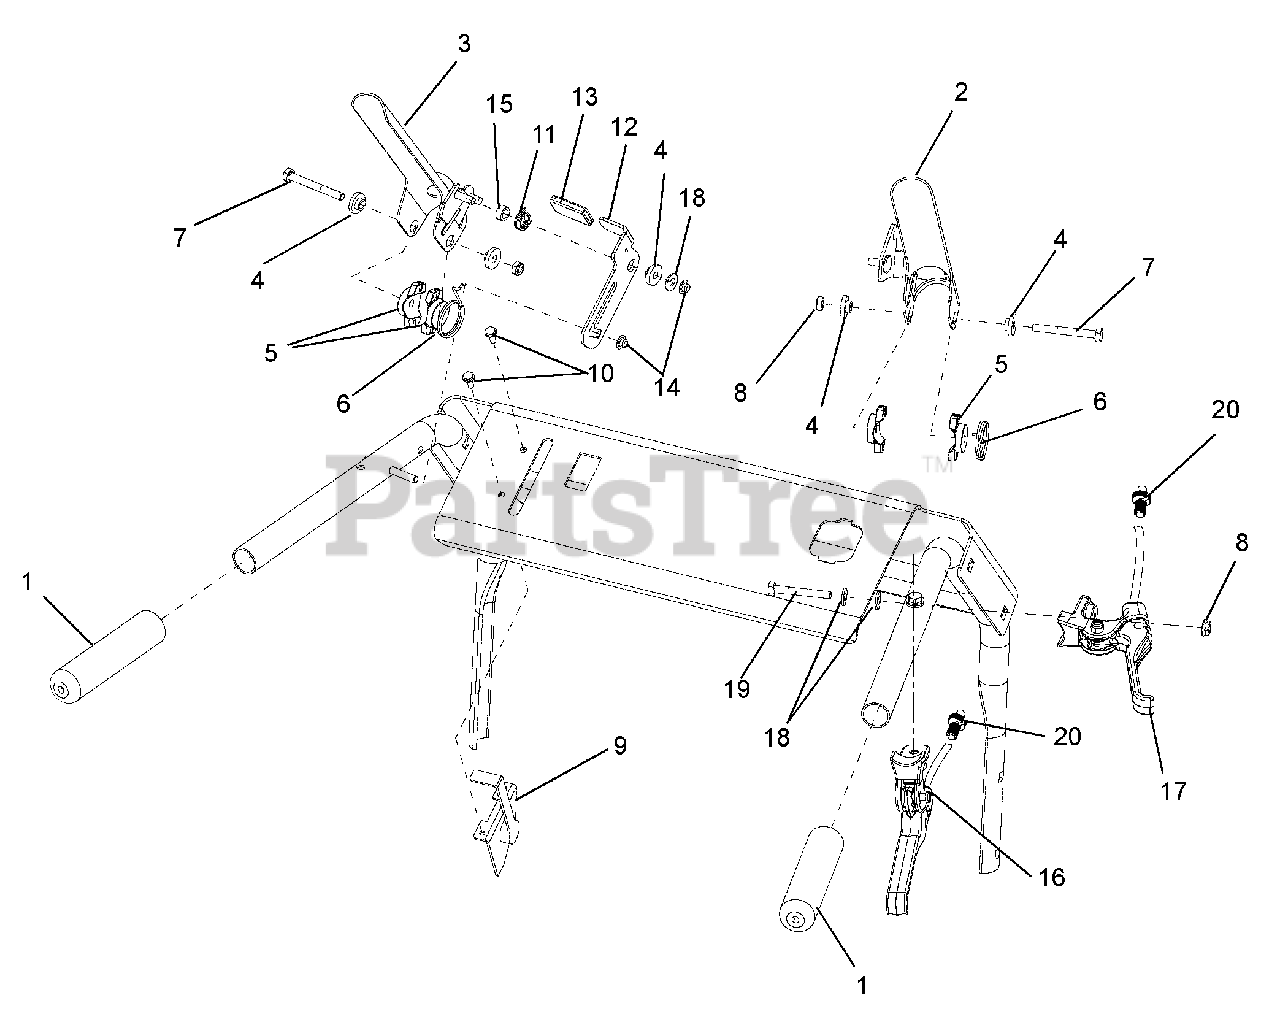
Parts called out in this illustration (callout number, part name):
1	Grip, Handle
2	Paddle, Pillow Brake
3	Weldment, Paddle Left Hand
4	Bushing, Flange .266 x .42 x .150 x .750
5	Spacer, Handlebar
6	Spring, Torsion
7	Bolt, Hex .25-20 x 2.25
8	Nut, Nylon Jam .250-20
9	Cable, Throttle/Choke
10	Screw Tapping 10-24 x .38
11	Spring, Torsion
12	Bracket - Lever, Interlock
13	Grip, Thumb Latch
14	Nut, Push .25
15	Tube, Spacer .33 x .50
16	Lever, Control With Cable Forward
17	Lever, Control With Cable Reverse
18	Washer, Flat Steel .281 x .62 x 0.65
19	Bolt, Hex .25-20 x 2.00
20	Cable Adjuster, Steel (Service Only)
